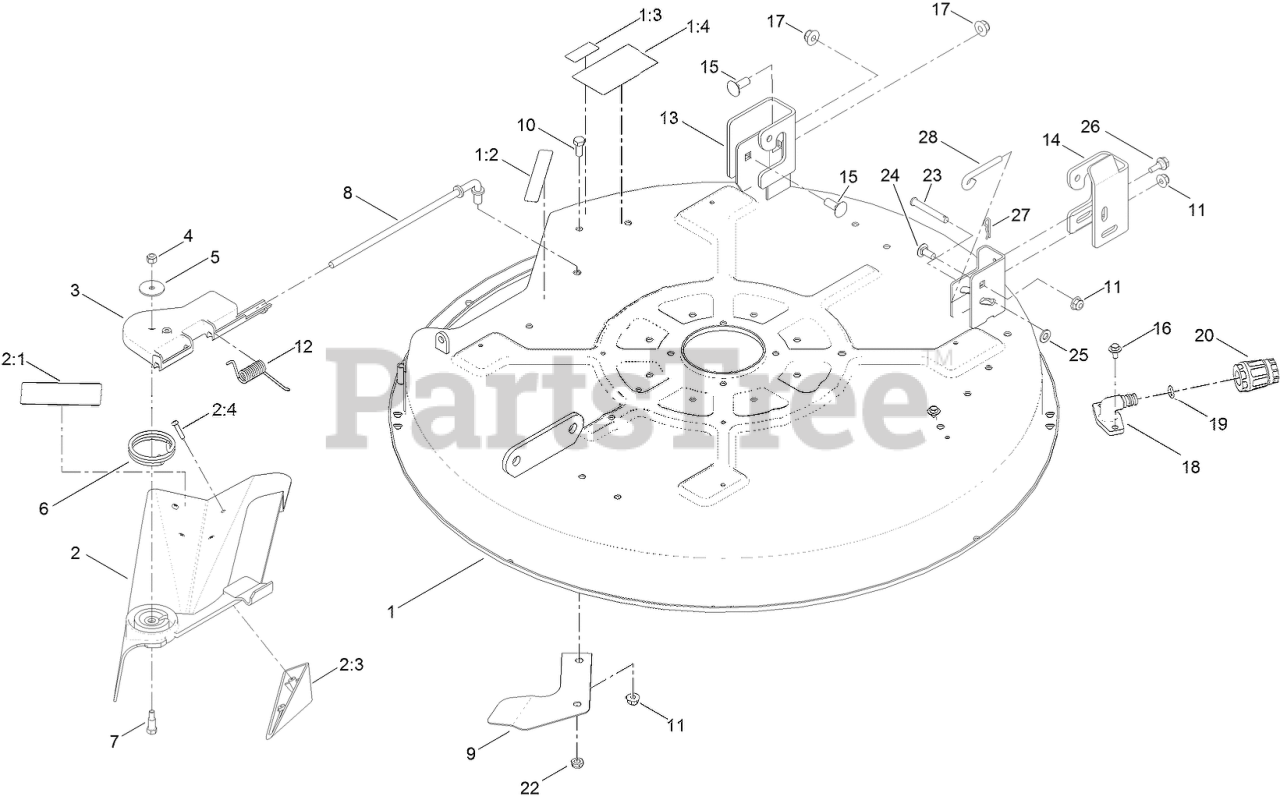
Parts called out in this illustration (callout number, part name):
1	32 INCH DECK AND DECAL ASM
1:2	DECAL-DANGER
1:3	DECAL-DANGER
1:4	DECAL-DANGER
2	32 INCH DEFLECTOR ASM
2:1	DECAL-DANGER
2:3	KICKER
2:4	SCREW-PPH
3	PIVOT-HINGE, DEFLECTOR
4	NUT-LOCK, NI
5	WASHER-FLAT
6	SPRING-TORSION
7	BOLT-SHOULDER
8	ROD-PIVOT
9	RAMP-DEFLECTOR
10	SCREW-HH
11	NUT-HF, NI
12	SPRING-TORSION
13	BRACKET-HANGER, RH
14	BRACKET-HANGER, LH
15	BOLT-CARR
16	SCREW-HHFTF
17	NUT-HF, NI
18	FITTING-WASHOUT
19	O-RING
20	CONNECTOR-HOSE
22	NUT-LOCK, NI
23	PIN-CLEVIS
24	SCREW-CARR
25	WASHER-PLAIN
26	SCREW-SHOULDER, HHF
27	PIN-COTTER
28	ROD-LEVEL, DECK
